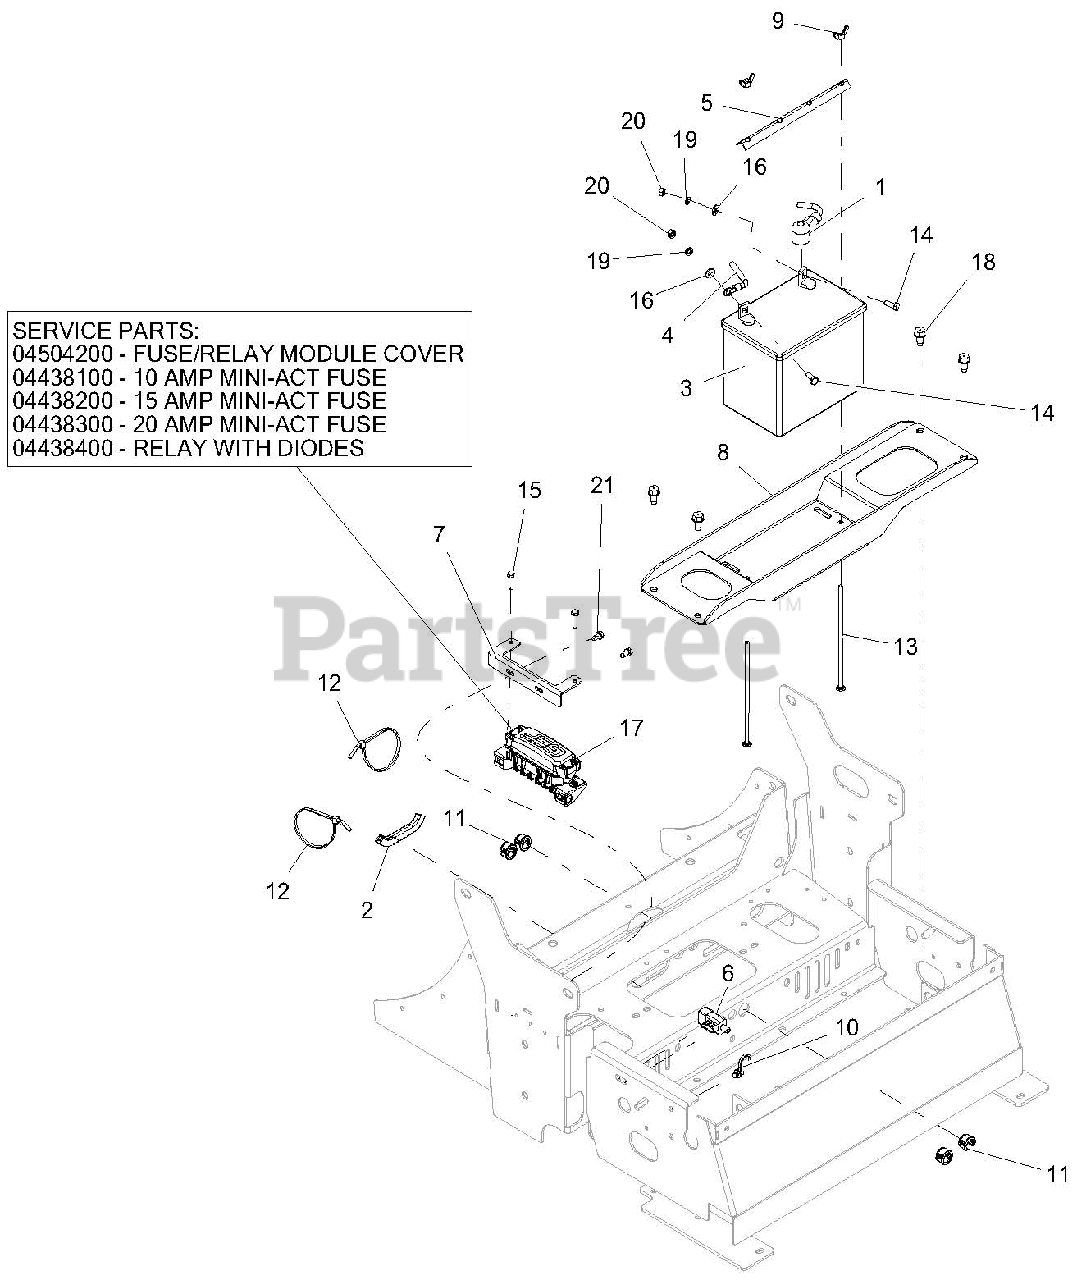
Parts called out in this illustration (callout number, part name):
1	CABLE, POS BATT W/ BOOTS 6 X 35
2	STRIP, COWL - 1.50 LG
3	BATTERY, 300 CCA 10U1L
4	CABLE, NEGATIVE BATTERY 35.00"
5	HOLD DOWN - BLK
6	SWITCH, SNAP IN -N.O./N.O
7	BRKT, FUSE HOLDER MOUNTING-RED
8	TRAY, BATTERY-RED
9	NUT-LOCKING WING 1/4-20
10	CABLE TIE W/ TREE
11	BUSH, PANEL SNAP .687X.875X.56
12	CABLE, TIE 5.50 LG
13	BLT-RDHDSQNK .25-20X7.50 G2 YWZC
14	BLT-HEX .25-20X.75 GR5 YWZC
15	@BLT-HEX M6-1.0X25 YWZC
16	WSHR-FL-STL.281X.62X.065 YWZC
17	HARNESS, PT400 GAS WIRE
17	FUSE/RELAY MODULE COVER
17	10 AMP MINI-ACT FUSE
17	15 AMP MINI-ACT FUSE
17	20 AMP MINI-ACT FUSE
17	RELAY WITH DIODES
18	SCR-TAP .38-16X.75 HWH TR YWZ
19	WSHR-LK .25X.062 REG YWZC
20	NUT-HEX .25-20 YWZC
21	SCR-TAP .25-20X.50 HWH TR YWZ
